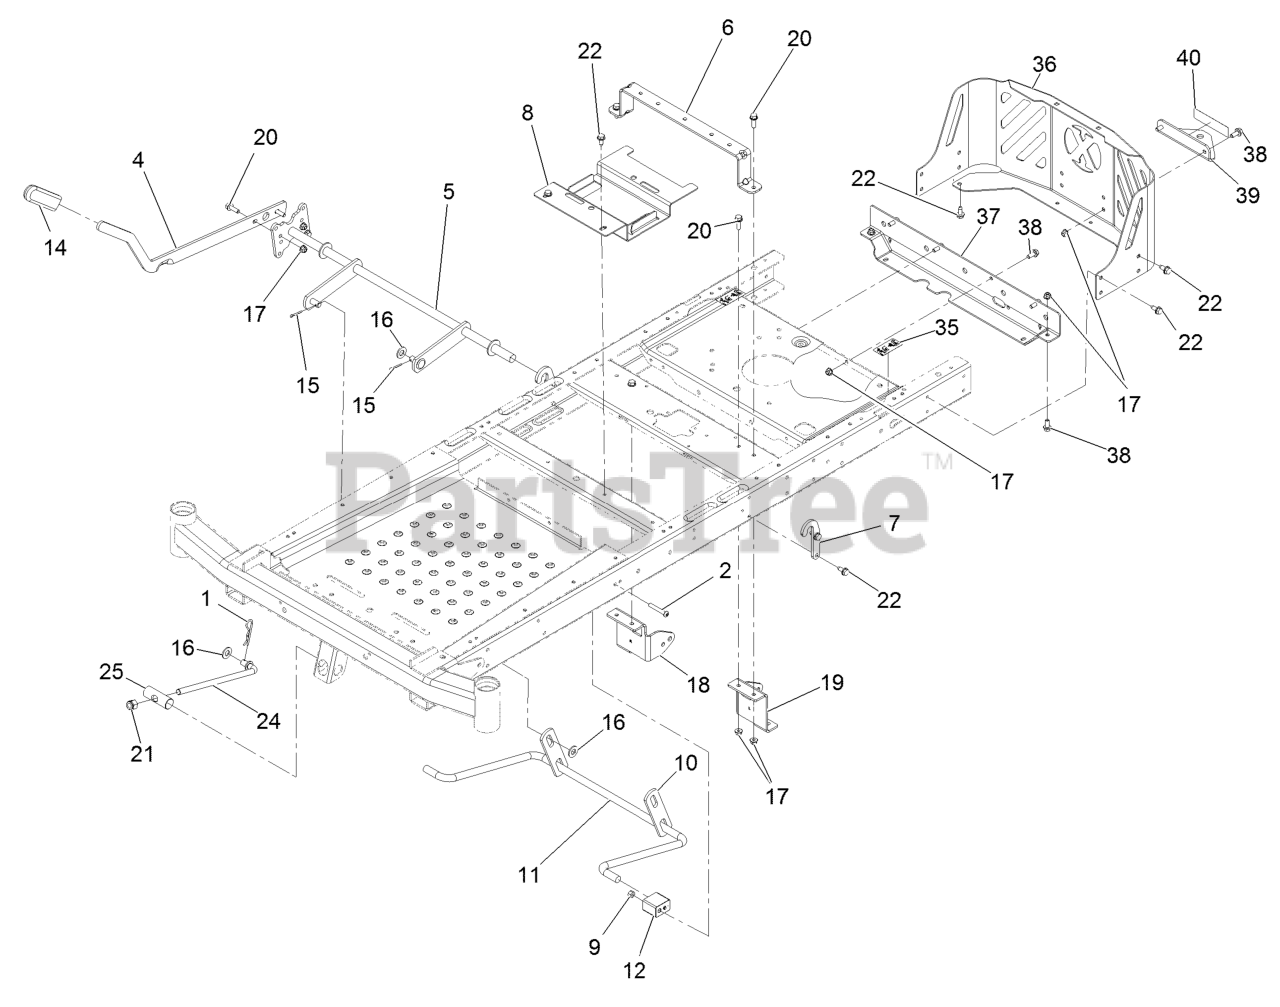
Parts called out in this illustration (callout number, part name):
1	PIN-COTTER
2	SCREW-HSBH
4	LEVER-LIFT
5	LIFT-DECK, WIDE
6	BRACE-SEAT, REAR
7	BRACKET-LIFT
8	BRACKET-BATTERY
9	NUT-LOCK, NI
10	LINK-LIFT
11	ARM-LIFT, REAR (WIDE)
12	BLOCK-PIVOT
14	GRIP-LEVER
15	PIN-COTTER
16	WASHER-FLAT
17	NUT-HF, NI
18	MOUNT-HYDRO, FRONT (RH)
19	MOUNT-HYDRO, FRONT (LH)
20	SCREW-HHF
21	NUT-HEX
22	Screw-HWH 5/16-18 X 3/4 Tf
24	ROD-MOUNT, DECK
25	PIN-PIVOT
35	DECAL-BYPASS
36	GUARD-ENGINE, WIDE
37	CROSSMEMBER-REAR, WIDE
38	SCREW-HHF
39	BRACKET-HITCH
